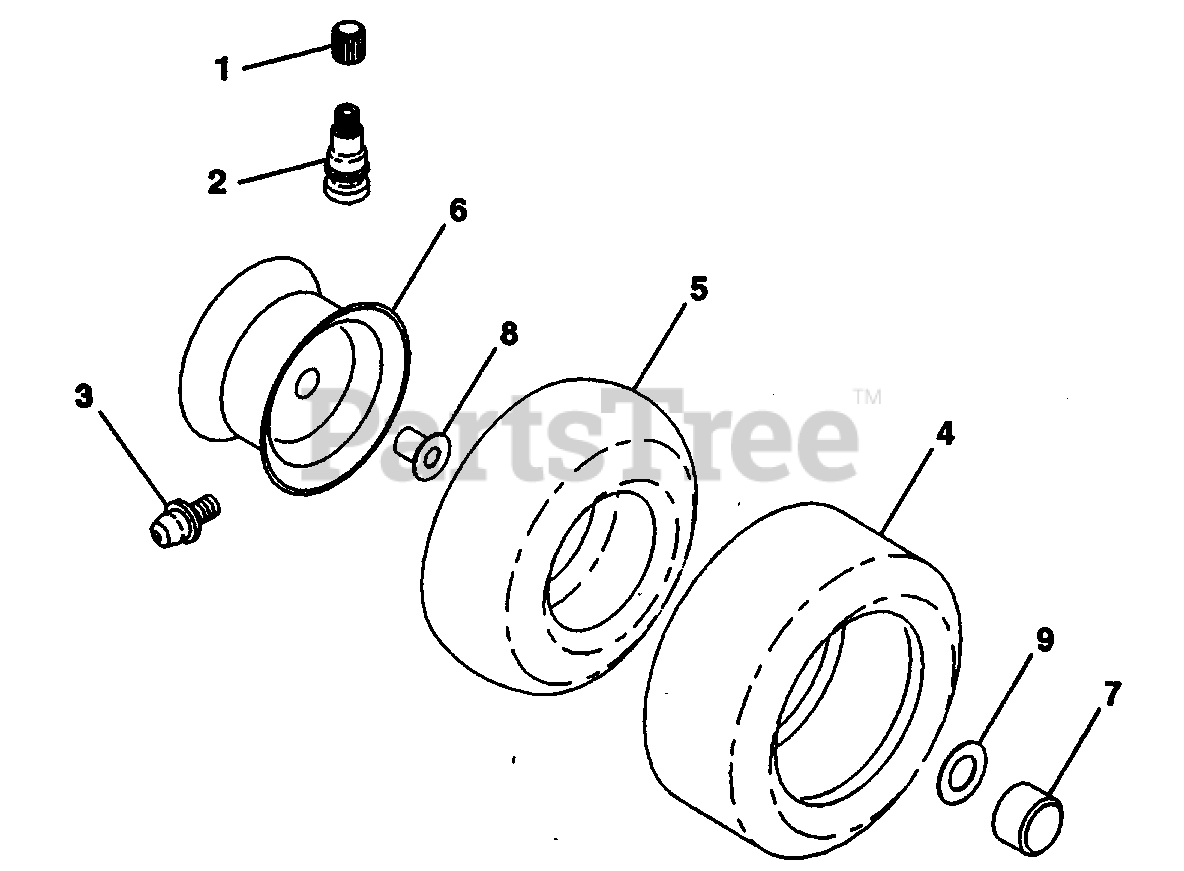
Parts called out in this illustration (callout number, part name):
1	Cap, Valve (AYP part number)
2	Stem, Valve (AYP part number)
3	Fitting, Grease (Front Only) (AYP part number)
4	Tire, Front
5	Tube, Tire, Front (Not Supplied, Service Item Only)
6	Rim, Front (AYP part number)
7	Cap, Axle (Front and Rear) (AYP part number)
8	Bearing, Flange (Front only) (AYP part number)
9	Washer 25/32 x 1-5/8 x 16 Gauge (AYP part number)
